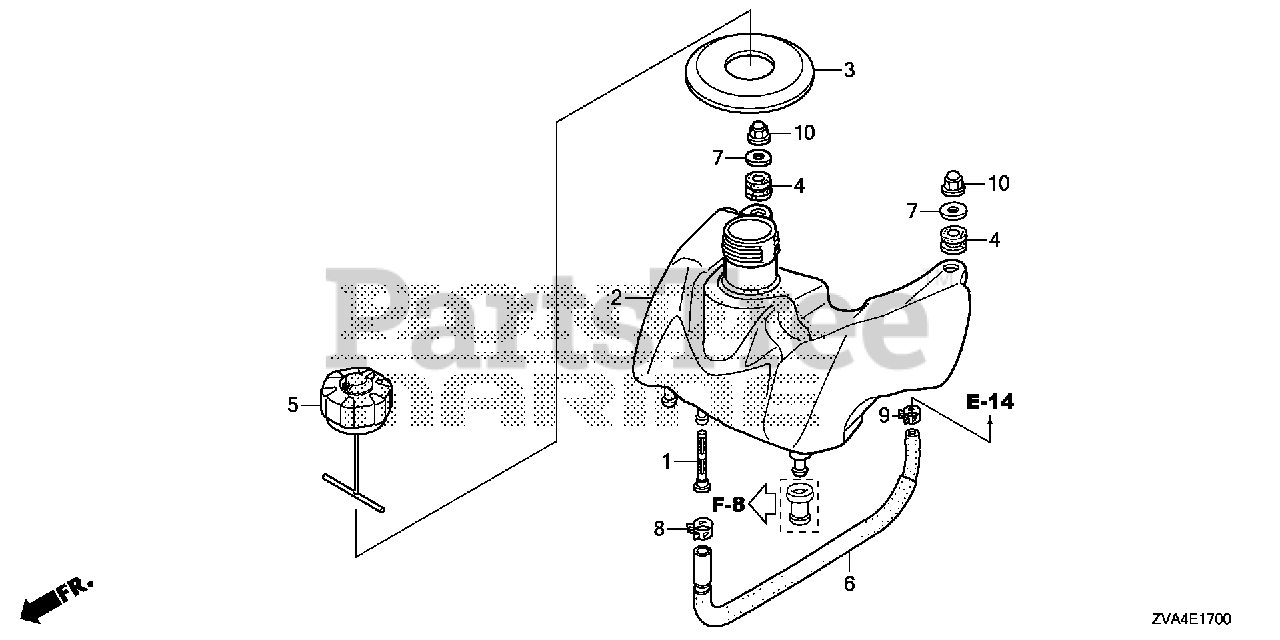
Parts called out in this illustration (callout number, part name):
1	FILTER, FUEL
2	TANK, FUEL (FOR U.S.A.)
3	RUBBER, TANK CAP
4	GROMMET, FUEL TANK
5	CAP ASSY., FUEL TANK
6	TUBE, FUEL
7	WASHER, PLAIN (6MM)
8	CLAMP, TUBE (D10.5) (ENGINE NO.)
9	CLAMP, TUBE (8.0)
10	NUT, CAP (6MM)
